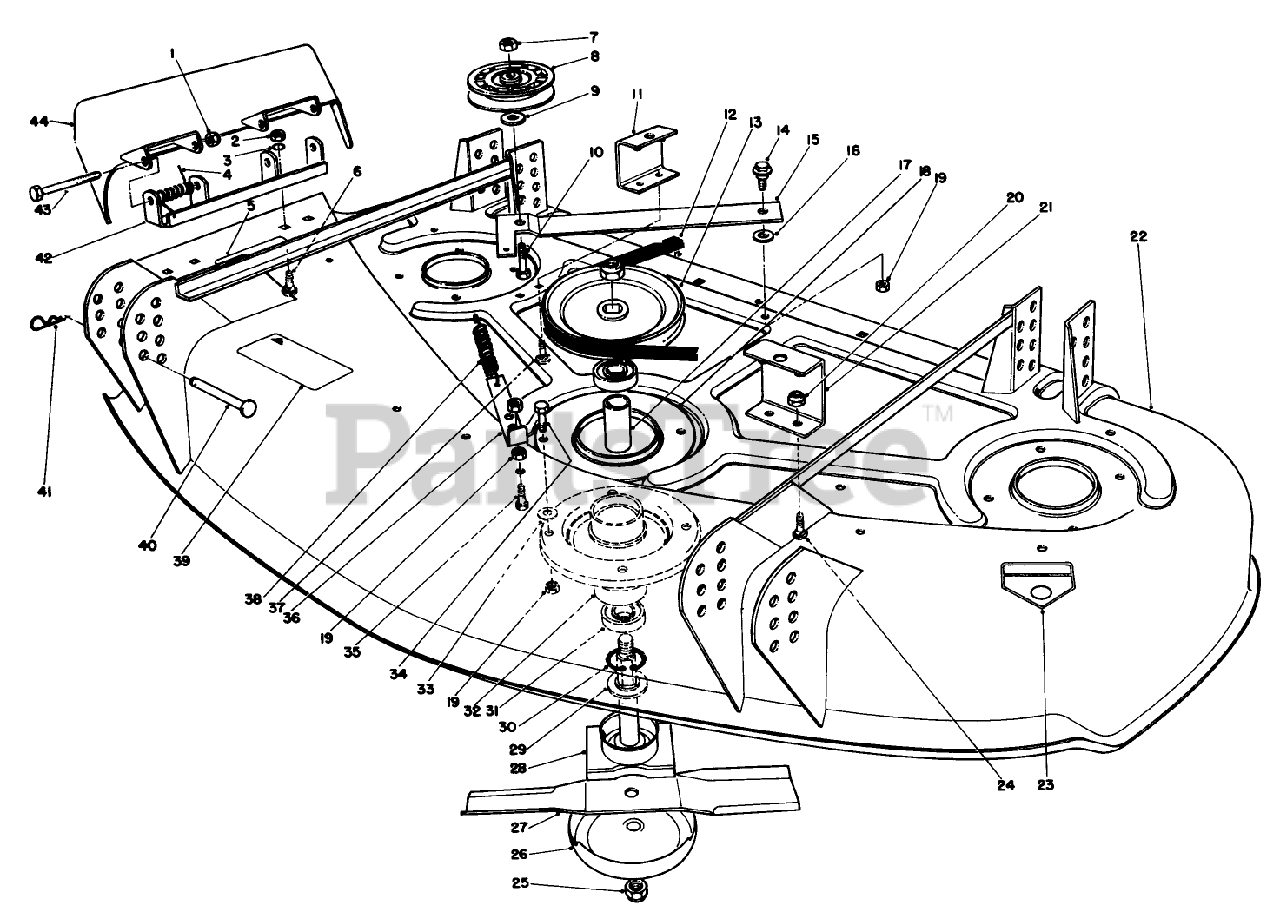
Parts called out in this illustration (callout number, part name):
1	NUT-HEX
2	NUT-HEX
3	SCREW-HH
4	SPRING
7	NUT-LOCK, CONE
9	WASHER-FLAT
10	SCREW-HH
12	V-BELT-DECK
14	SCREW-SHOULDER
16	WASHER
19	NUT-LOCK, CONE
20	NUT-LOCK, NI
23	DECAL-DANGER
24	SCREW-CARR
25	NUT-SPECIAL
26	Cup
28	SPINDLE SHAFT WA
29	SPACER-SPINDLE
31	BEARING-BALL
33	WASHER-FLAT
34	SCREW-HH
35	SCREW-HH
37	SCREW-CARR
38	SPRING-EXTENSION, DECK
40	PIN-CLEVIS
41	PIN-HAIR
42	PIVOT BRKT WA
43	SCREW-HH
